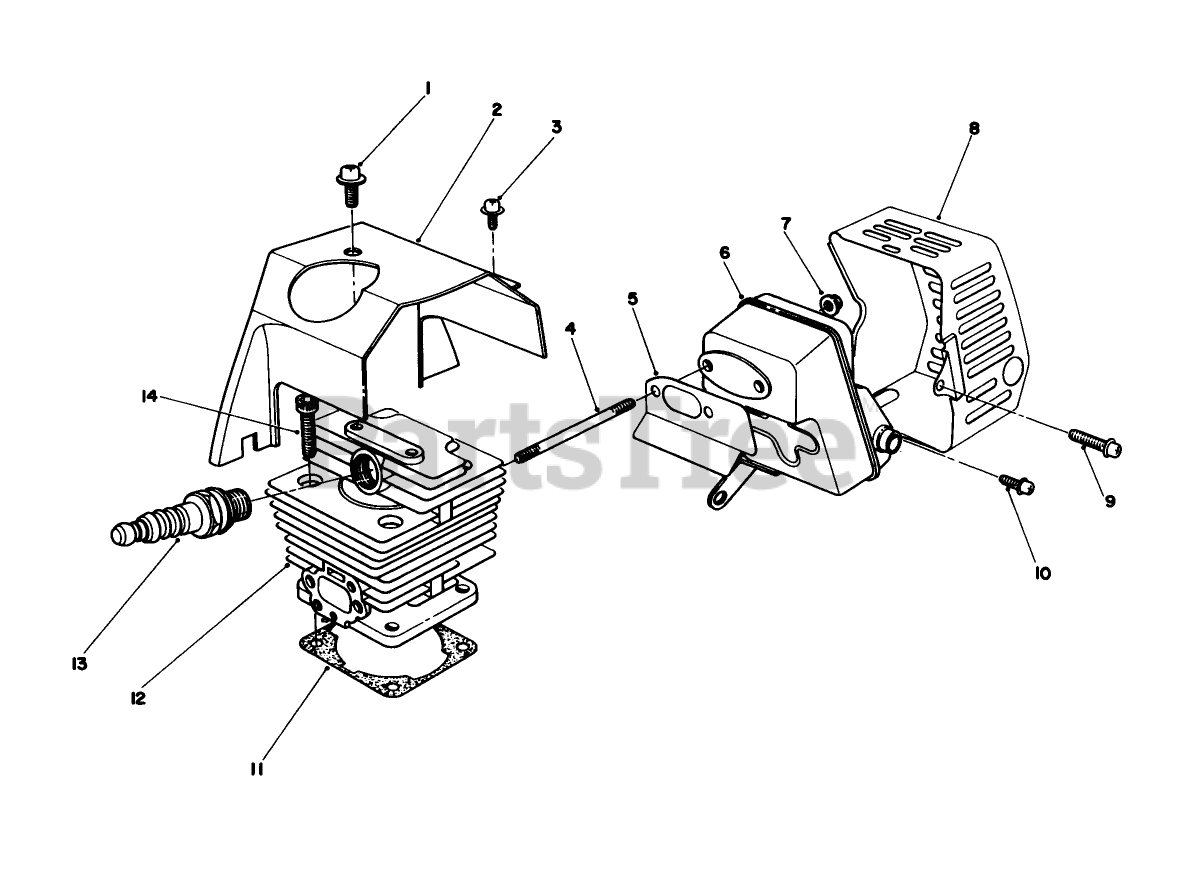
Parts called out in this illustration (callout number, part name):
6	MUFFLER
10	SCREW & WASHER
12	CYLINDER
